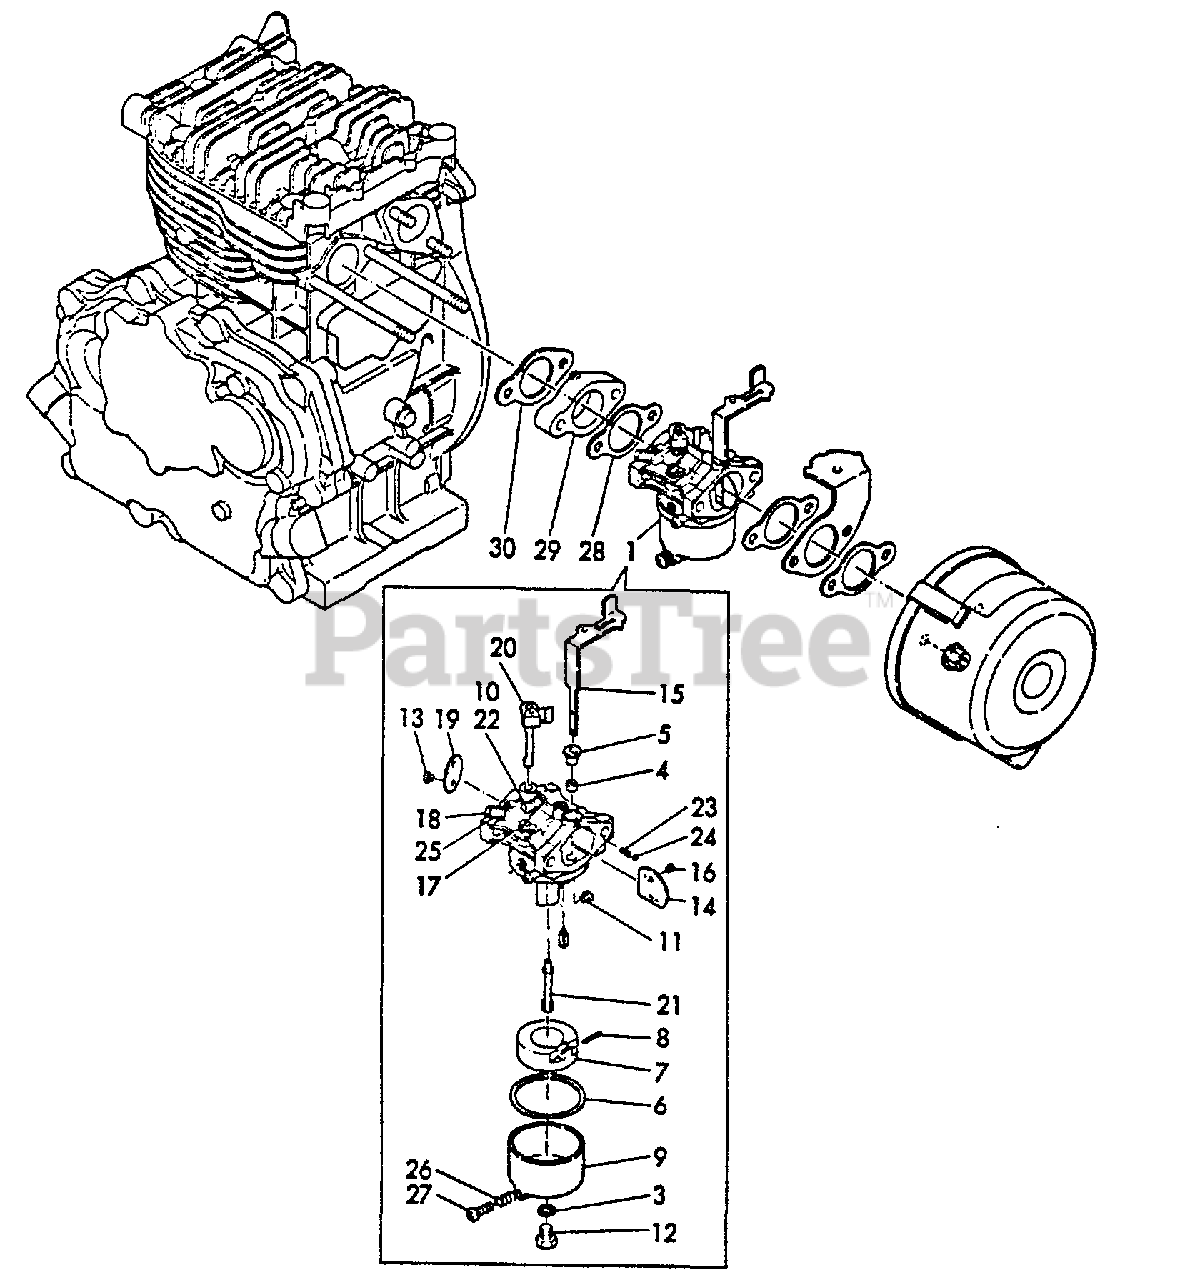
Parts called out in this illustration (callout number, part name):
1	CARBURETOR
3	WASHER
4	RING, CHOKE SHAFT
5	RING, CHOKE LEVER
6	GASKET, FLOAT CHAMBER
7	FLOAT
8	PIN
9	BODY
11	JET, MAIN
12	BOLT
13	SCREW
14	VALVE, CHOKE
15	LEVER, CHOKE
17	JET, PILOT
18	SCREW
19	VALVE, THROTTLE
20	SHAFT, THROTTLE
21	NOZZLE, MAIN
22	SCREW
23	SPRING, CHOKE
24	BALL, CHOKE
27	SCREW
28	GASKET, INTAKE
29	INSULATOR
30	GASKET, INTAKE
